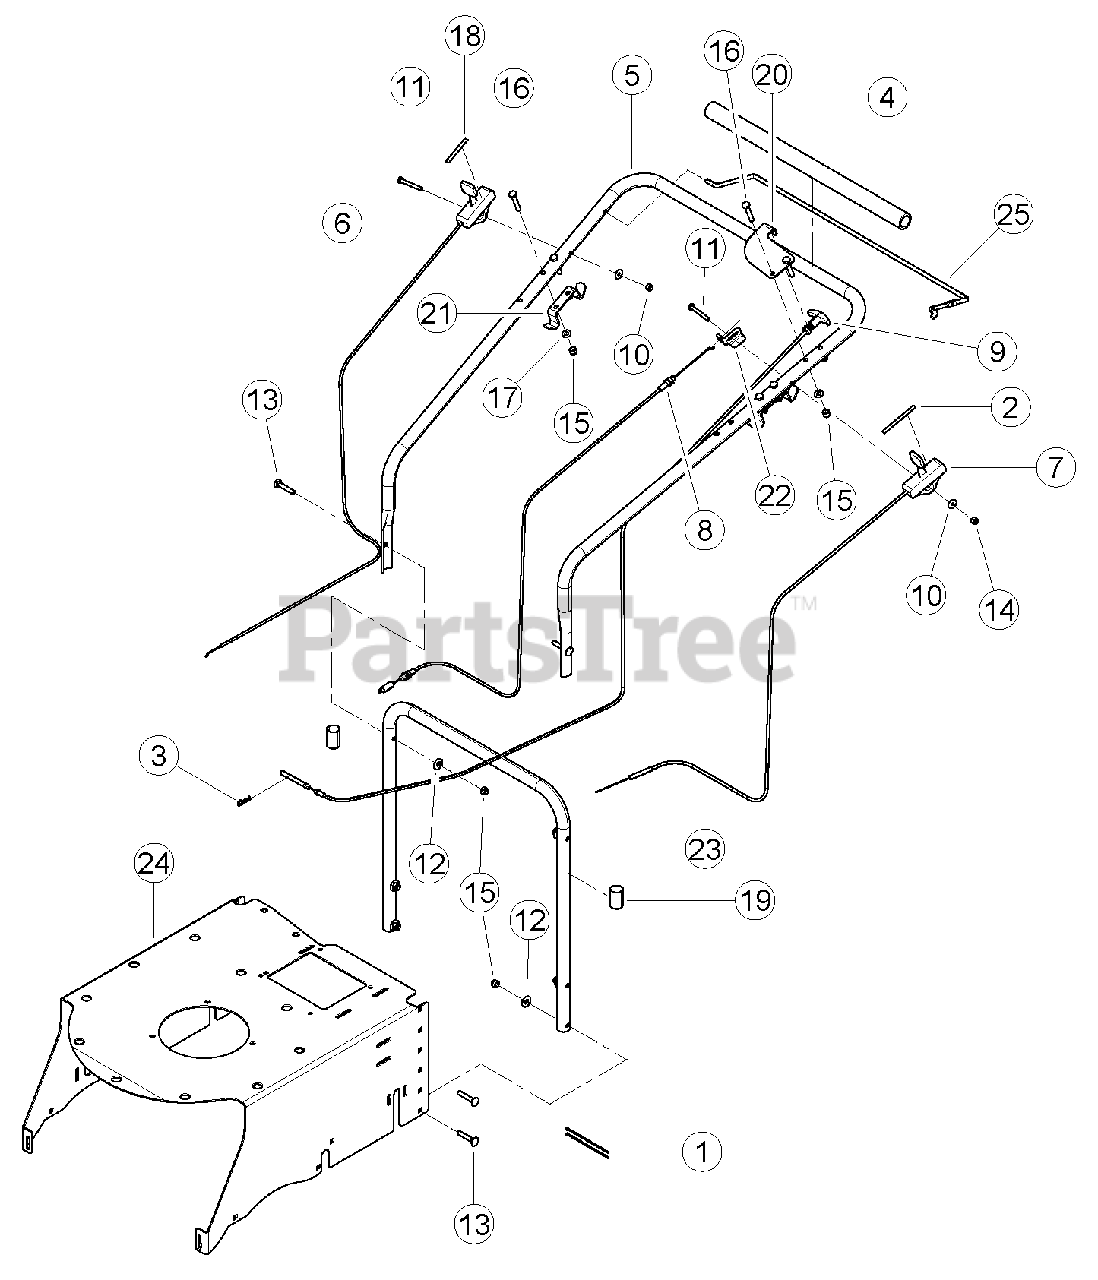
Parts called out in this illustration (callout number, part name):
1	STRAP, NYLON TIE
2	DECAL, 3 SPEED
3	CLIP, HAIRPIN ZP
4	PAD, FOAM HANDLEBAR
5	HANDLEBAR, BEARVAC UPPER
6	CONTROL, THROTTLE
7	CONTROL, TRANS. SHIFT
8	CONTROL, CLUTCH ENGAGEMENT
9	CONTROL, HEIGHT ADJUSTMENT
10	WASHER, 1/4 FLAT
11	BOLT, 1/4 X 2 HEX HD
12	WASHER, 5/16 FLAT
13	BOLT, 5/16 X 1-3/4 CRG GR5 ZP
14	NUT, 1/4 NYLOCK
15	NUT, 5/16 NYLOCK
16	BOLT, 5/16 X 1-3/4 HEX HD
17	WASHER, 5/16 SAE FLAT
18	DECAL, THROTTLE CONTROL
19	CAP, PLASTIC 7/8 IN
20	BRACKET, BEARVAC CABLE MOUNT
21	BRACKET, BAG HANGER
22	BRACKET, CLUTCH CABLE
23	HANDLEBAR, BEARVAC LOWER
24	SUPPORT, BEARVAC FRAME
25	BAIL, BEARVAC CLUTCH CONTROL
